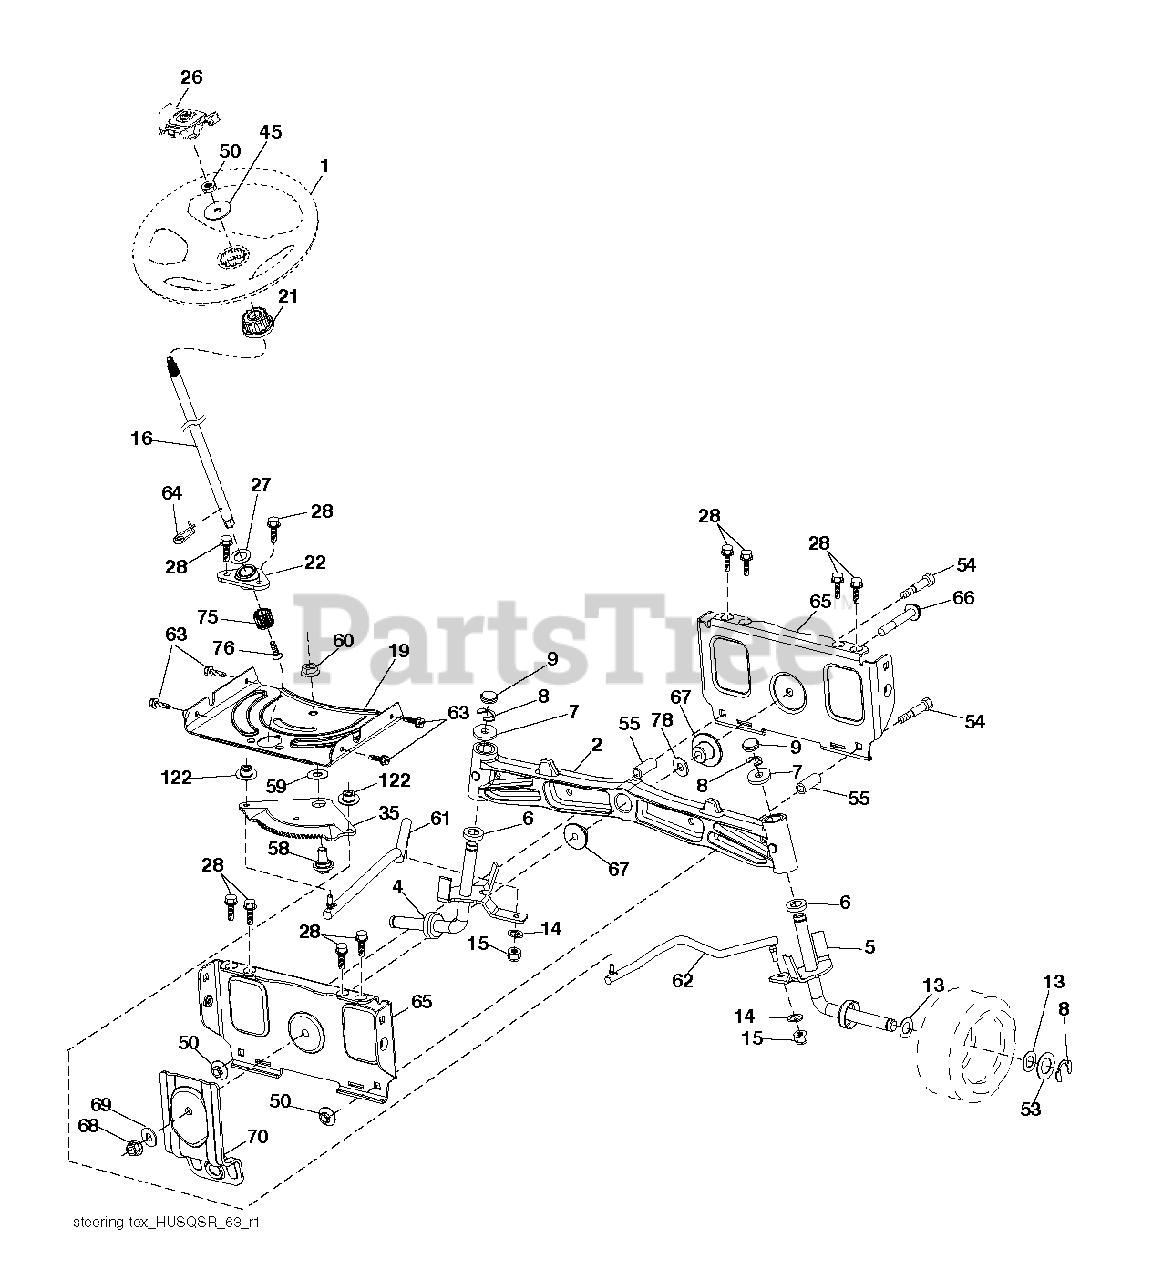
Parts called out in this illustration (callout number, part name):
1	WHEEL.STEER.HUSQ.SR.498.OVMLD
2	AXLE.CAST.IRON
4	SPINDLE.WELDED.LH.16"TEX
5	SPINDLE.WELDED.RH.16"TEX
6	THRUST WASHER
9	CAP.SPINDLE.BLACK
14	SLW 3/8 STD
15	NUT CROWNLOCK 3/8-24
16	SHAFT.STEER.2HIGH.SPLND.PLATED
19	PLATE.STEER.DDL.NLT/NG
21	ADAPTER.WHEEL.STEER.SPLND.ALUM
22	BEARING.SHAFT.STEER.LOWER.625
26	INSERT.CAP.WHL.STRG.HUSQ.PREM
28	SCREW, 3/8-16X3/4
35	GEAR.SECTOR.PLATE.DDL.
45	WASHER.3/8ID.2-3/8OD.12GA.PLTD
50	NUT LOCK FLG 3/8-16 UNC
53	WASHER.HARDENED
55	SPACER.BRACE.AXLE
58	BOLT.SHOULDER.SECTOR.P
59	WASHER.THURST.SECTOR.S
60	NUT FLANGE LOCK 5/8-11
61	DRAGLINK.LH.BALLSTUD.D
62	DRAGLINK.RH.BALLSTUD.D
63	SCREW
64	RETAINER.CLIP.SPRING.S
65	BRACE.AXLE.FRONT.NLT/N
66	BOLT HEX FGHD 7/16-14 X 3 SERR
67	BUSHING.PM.FRONT AXLE
68	NUT.LOCK.FLANGE.7/16
69	WASHER.1.5X.505X.118
70	BRACKET.FRT.DECK.SUSP.RR.MT431
75	PINION.ZINC PLATED
76	SCREW HEAD SOCKET LRVB
78	THRUST WASHER
122	CAP.GEAR.SECTOR.TEX
